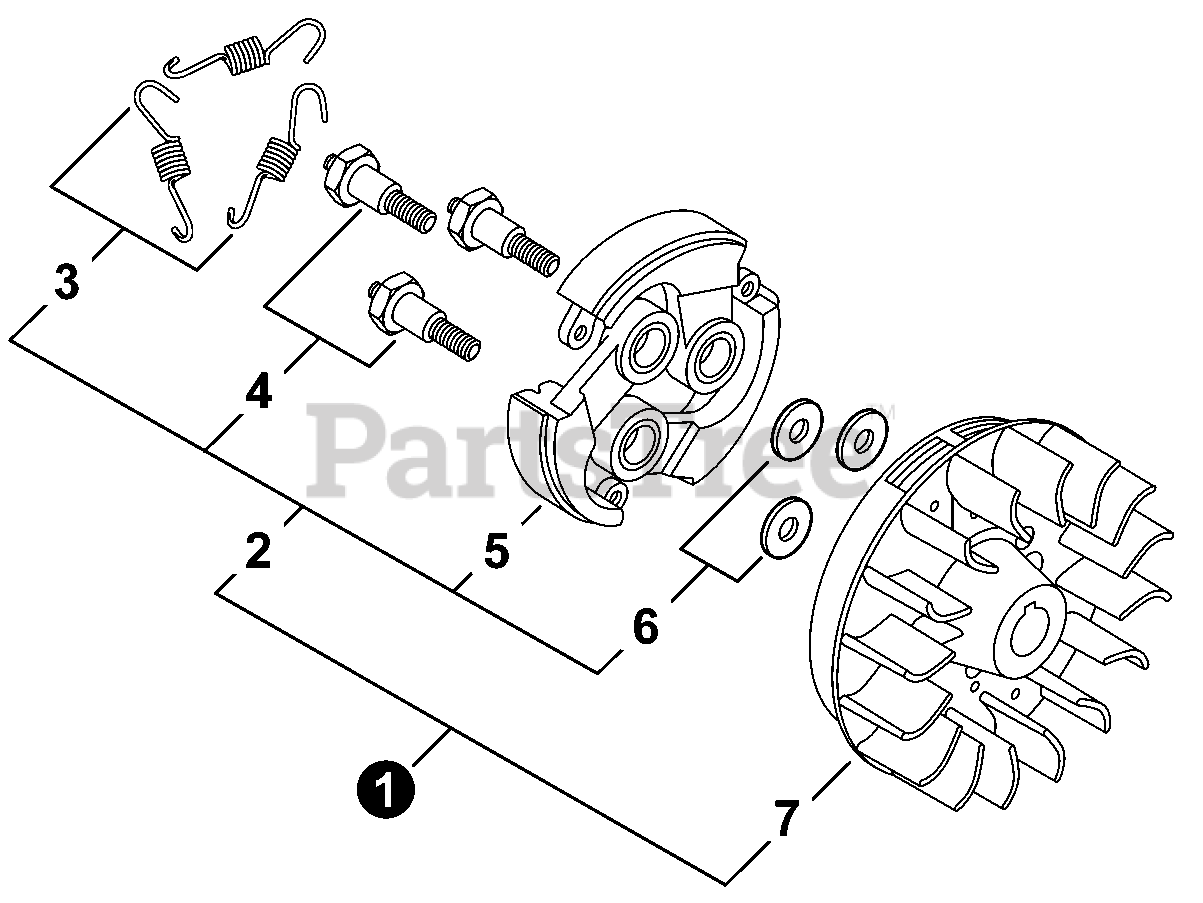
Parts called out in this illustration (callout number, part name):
1	FLYWHEEL KIT
2	CLUTCH ASSY
3	SPRING, CLUTCH
4	BOLT, CLUTCH
5	SHOE, CLUTCH
6	WASHER 6 MM
7	FLYWHEEL
